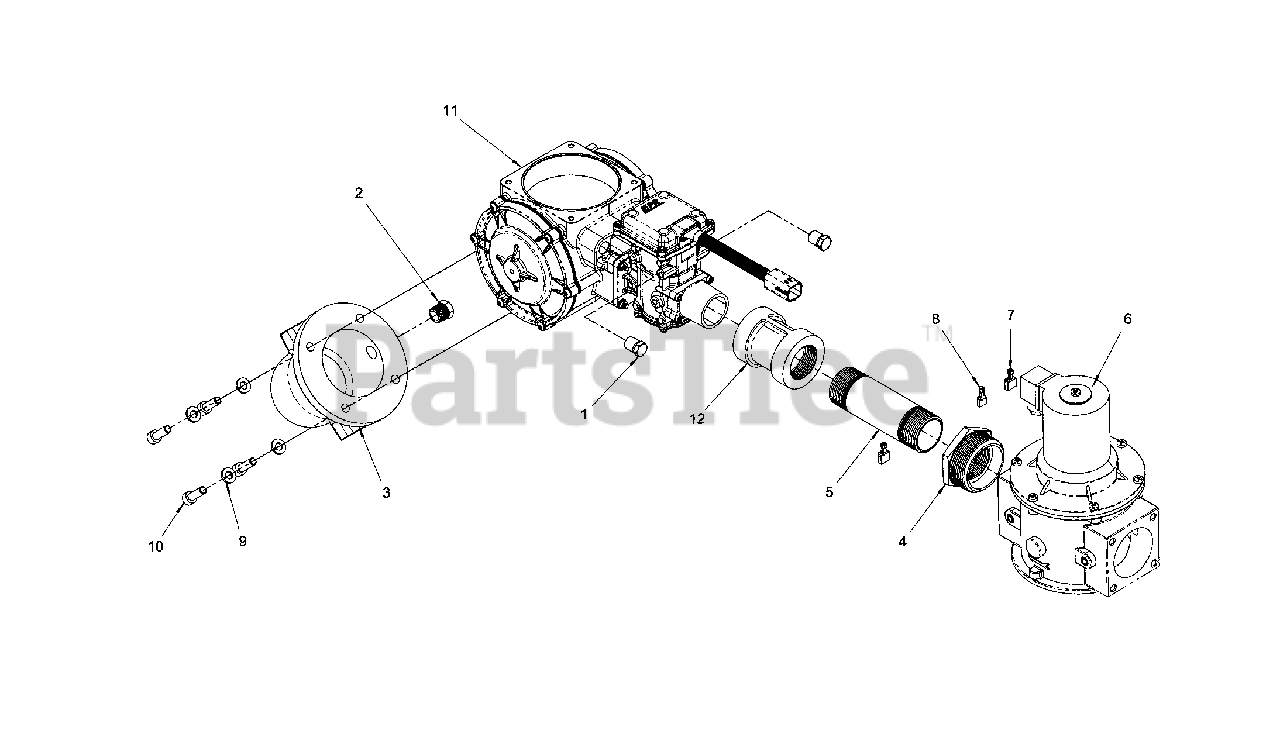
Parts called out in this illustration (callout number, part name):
1	* PLUG
2	* PLUG
3	* ELBOW
4	* BUSHING
5	* NIPPLE
6	LOCK OFF VALVE
7	* TERMNAL
8	* TERMNAL
9	* WASHER
10	* BOLT
11	EPR KIT
12	* COUPLER
